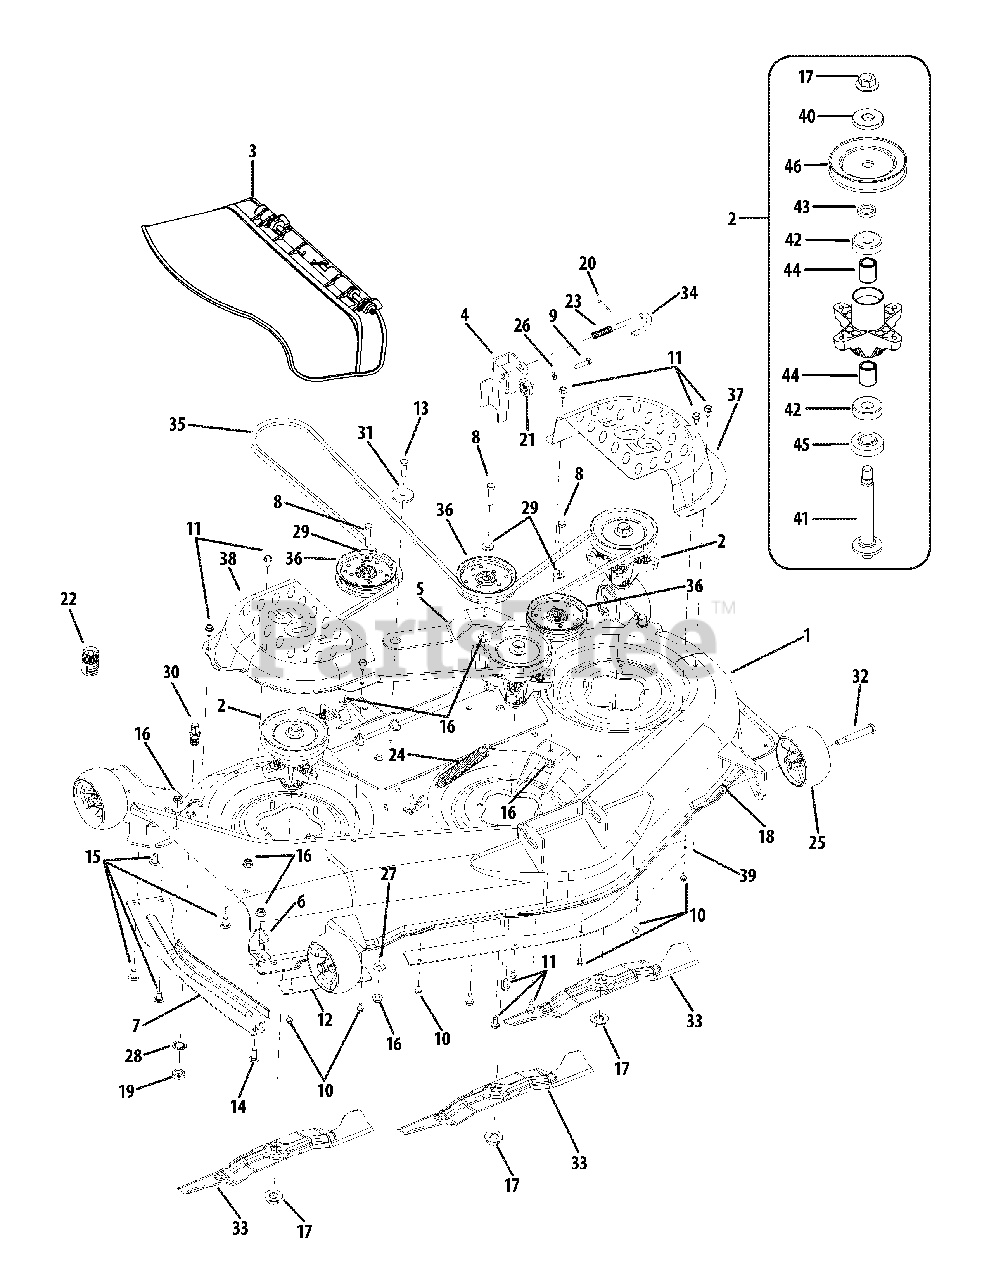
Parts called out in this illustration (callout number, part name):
1	Deck Housing
2	Spindle Assembly
3	Discharge Chute Assembly
4	Deck Hanger Bracket
5	Idler Arm
6	Stop Bracket
7	Finger Guard
8	Hex Cap Screw, 3/8-16 x 1.75
9	Hex Cap Screw, 5/16-18 x 1.25
10	Hex Washer Head Screw, 1/4-20 x .5
11	Hex Washer Head Screw, 5/16-18 x .750
13	Hex Cap Screw, 3/8-16 x 1.25
14	Carriage Screw, 3/8-16 x 1.00
15	Carriage Screw, 3/8-16 x .75
16	Hex Insert Flange Lock Nut, 3/8-16
17	Hex Flange Nut, 5/8-18
18	Hex Flange Lock Nut, 3/8-16
19	Hex Nut, M16-1.5
20	Cotter Pin, 1/8 x 1.25
21	Deck Adjustment Gear
22	Water Nozzle Adapter
23	Compression Spring, .535 x 1.75
24	Extension Spring, .94 x 6.74
25	Deck Ball Wheel, 5.0
26	Lock Washer, 5/16
27	Bell Washer, .45 x 1.0 x .062
28	Internal Tooth Lock Washer, 5/8
29	Flat Washer, .38 x .93 x .110
30	Deck Wash Nozzle
31	Shoulder Spacer, .884 x .190
32	Shoulder Screw, .5 x 2.5 x 3/8-16
33	Blade, 2 in 1, 17.9
34	Deck Hanger Rod
35	V-Belt Type A Sec x 134
36	Idler Pulley, 4.25 Dia
37	Belt Cover, LH
38	Belt Cover, RH
39	Center Skirt
40	Flat Washer, .76 x 1.50 x .12
41	Spindle Shaft, 5.75
42	Ball Bearing
43	Spacer, .79 x 1.25 x .175
44	Spacer, .80 x 1.10 x 1.32
45	Spacer, .79 x 1.82 x .55
46	V-Type Pulley, 5.39
